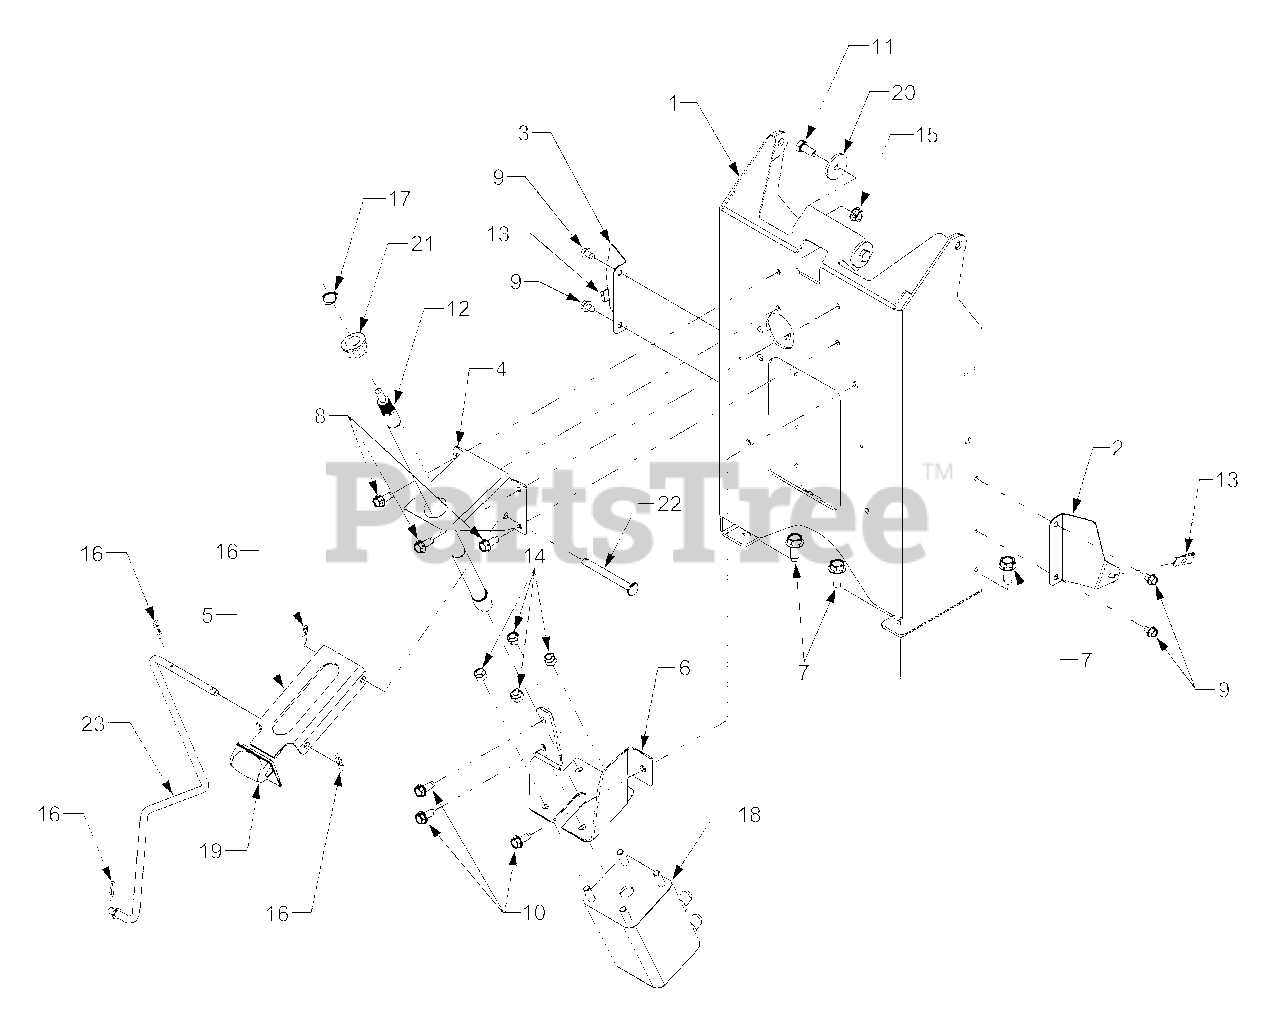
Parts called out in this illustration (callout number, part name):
1	Pedestal
2	Bracket, Dash Mtg. RH
3	Bracket, Dash Mtg. LH
4	Bracket, Steering Column
5	Bracket, Brake Lever
6	Bracket, Pump Mtg
7	Screw, Hex Wash, Hd Tapp 3/8-16 x .75
8	Screw, Hex Wash, Hd Tapp 1/4-20 x .75
9	Screw, Hex Wash, Hd Tapp 1/4-20 x .375
10	Screw, Hex Wash, Hd Tapp 5/16-18 x .75
11	Screw, Hex Cap 5/16-18 x .75 GR5
12	Shaft, Steering
13	Nut, Speed, 1/4-20
14	Nut, Hex Nylon Insert Lock, 5/16-24 GR8
15	Nut, Hex Flange Lock, 5/16-18
16	Pin, Internal Cotter
17	Ring, Snap, .75 ID
18	Pump, Hydraulic Steering
19	Lever, Parking Brake
20	Washer, Flat, .33 x 1.25 x .12
21	Bearing, Hex Flange, .75 ID
22	Pin, Parking Brake Pivot
23	Rod, Parking Brake
